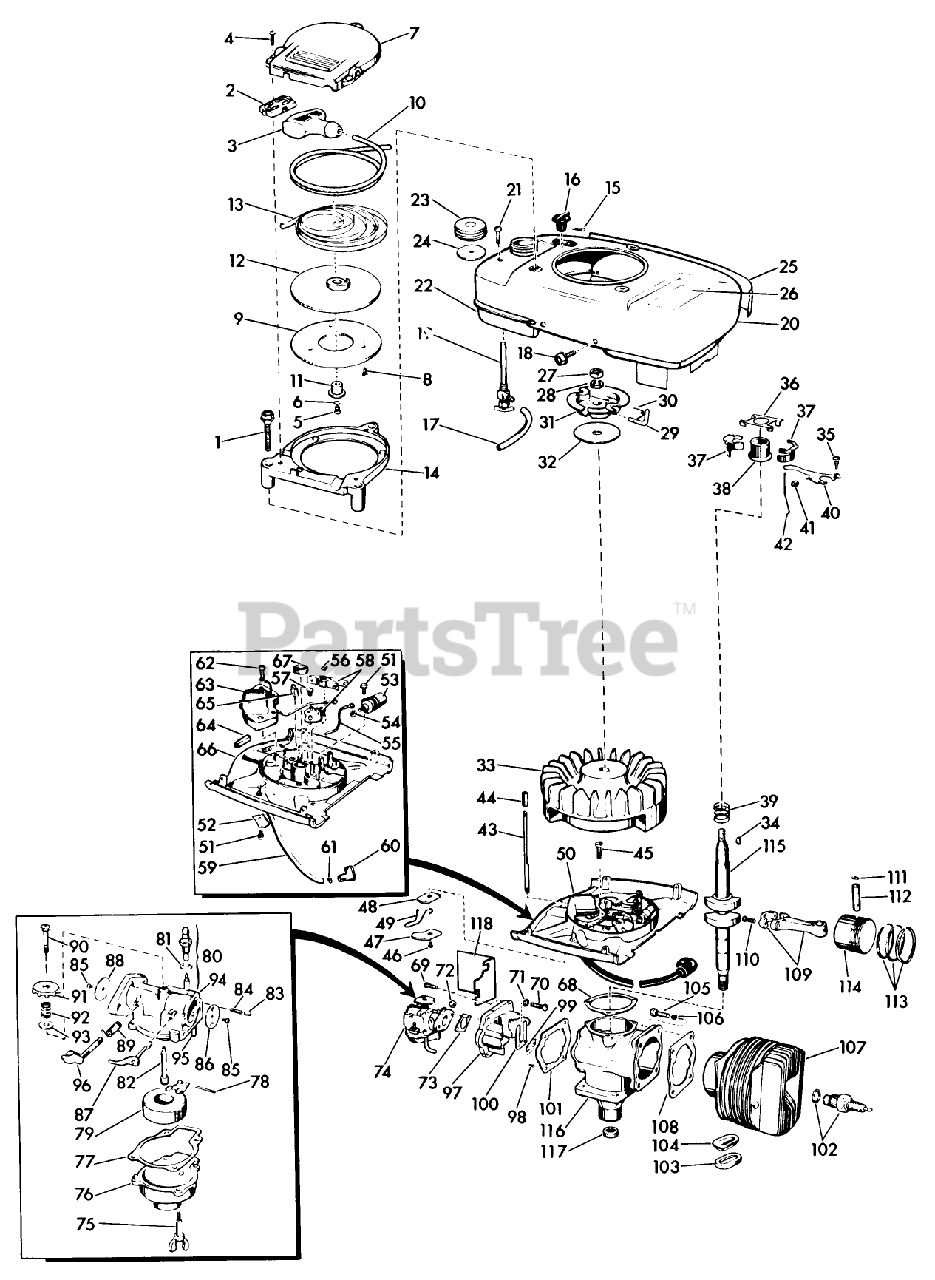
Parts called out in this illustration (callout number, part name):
13	RECOIL SPRING
15	Cotter Pin-Choke Knob
16	KNOB, CHOKE BAR
18	SCREW S
19	VALVE&SCREEN SM
23	Gas Cap
29	PIN - STARTER
38	COLLAR S
40	GOVERNER LEVER AY
41	WEAR BLOCK S
42	GOVERNOR ROD S
46	Screw Shut-off Switch
56	Spring Clip-Breaker Post
58	BREAKER AY. S
60	Cover-Rubber
65	Oiler Wick
68	GASKET S
72	STOP NUT
73	GASKET S
85	Screw-Choke Disc
86	Disc-Choke
87	CHOKE SHAFT&LVR AY
89	SPRING
90	NEEDLE AY. S
92	Spring-Ndl. Adj.
99	PLATE-BACKUP, REED
102	Spark Plug
110	Screw-Connecting Rod
115	Crankshaft
